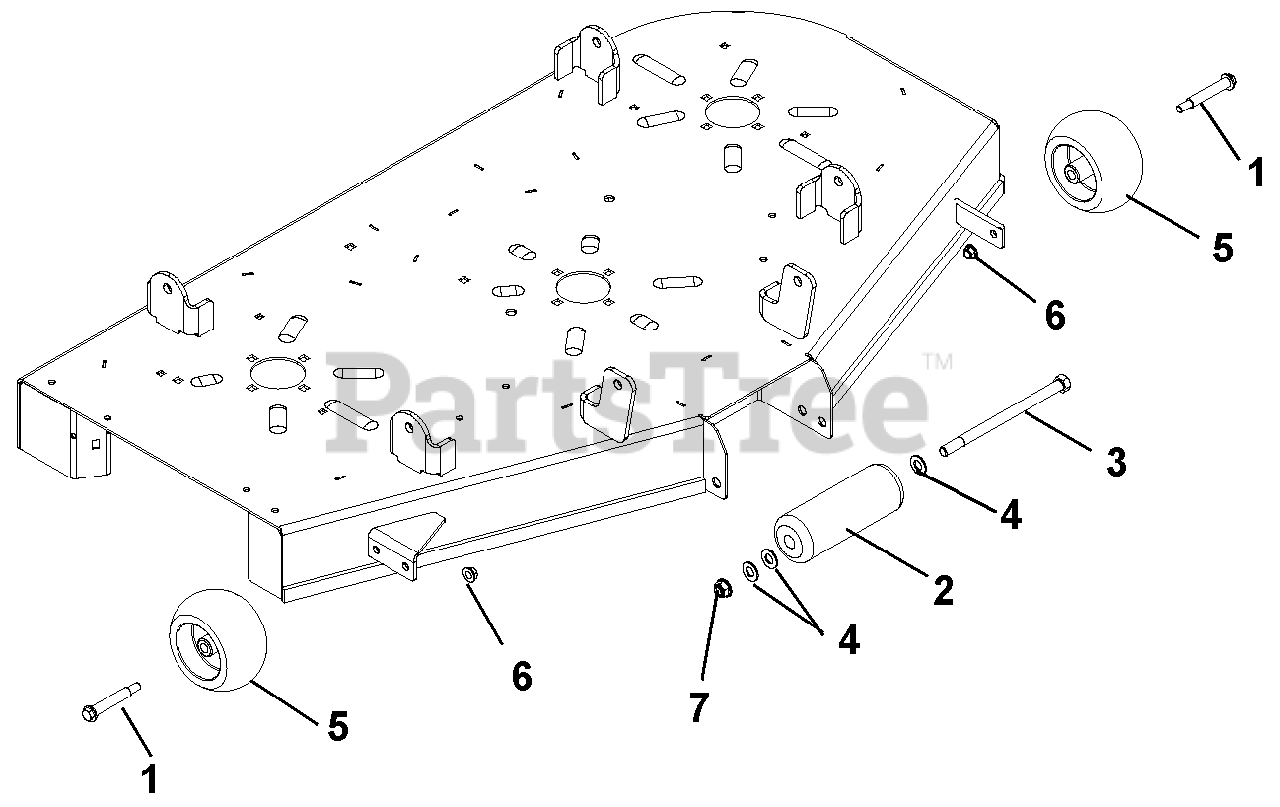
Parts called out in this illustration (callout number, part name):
1	BLT-SHLDR .38-16X2.50 HWH G5
3	@BLT-HEX .50-13X8.00 GR5 YWZC
4	WSHR-FL-NYL .518X1.000X.080
5	ANTI-SCALP WHEEL - 5X OS
6	@NUT-LK-TOP-FLG .38-16 YWZC
7	@NUT-LK-NYL .50-13 YWZC
